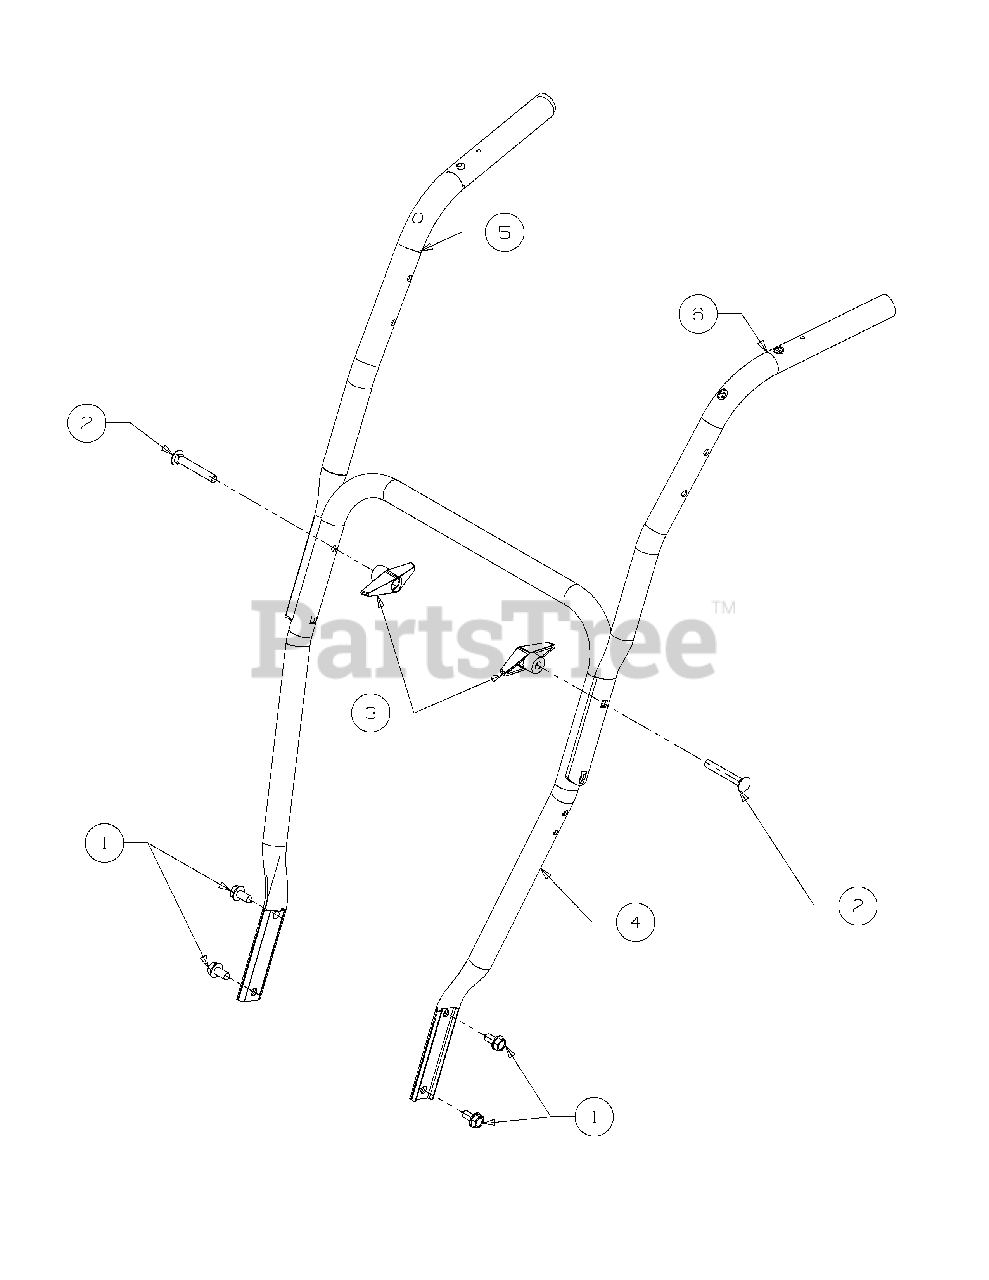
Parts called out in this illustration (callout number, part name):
2	Bolt-Carriage 5/
3	Knob-Wing Nut
4	Handle-Lower Snow
5	Handle-Upper RH W/Hole
6	Handle-Upper LH W/Hole
